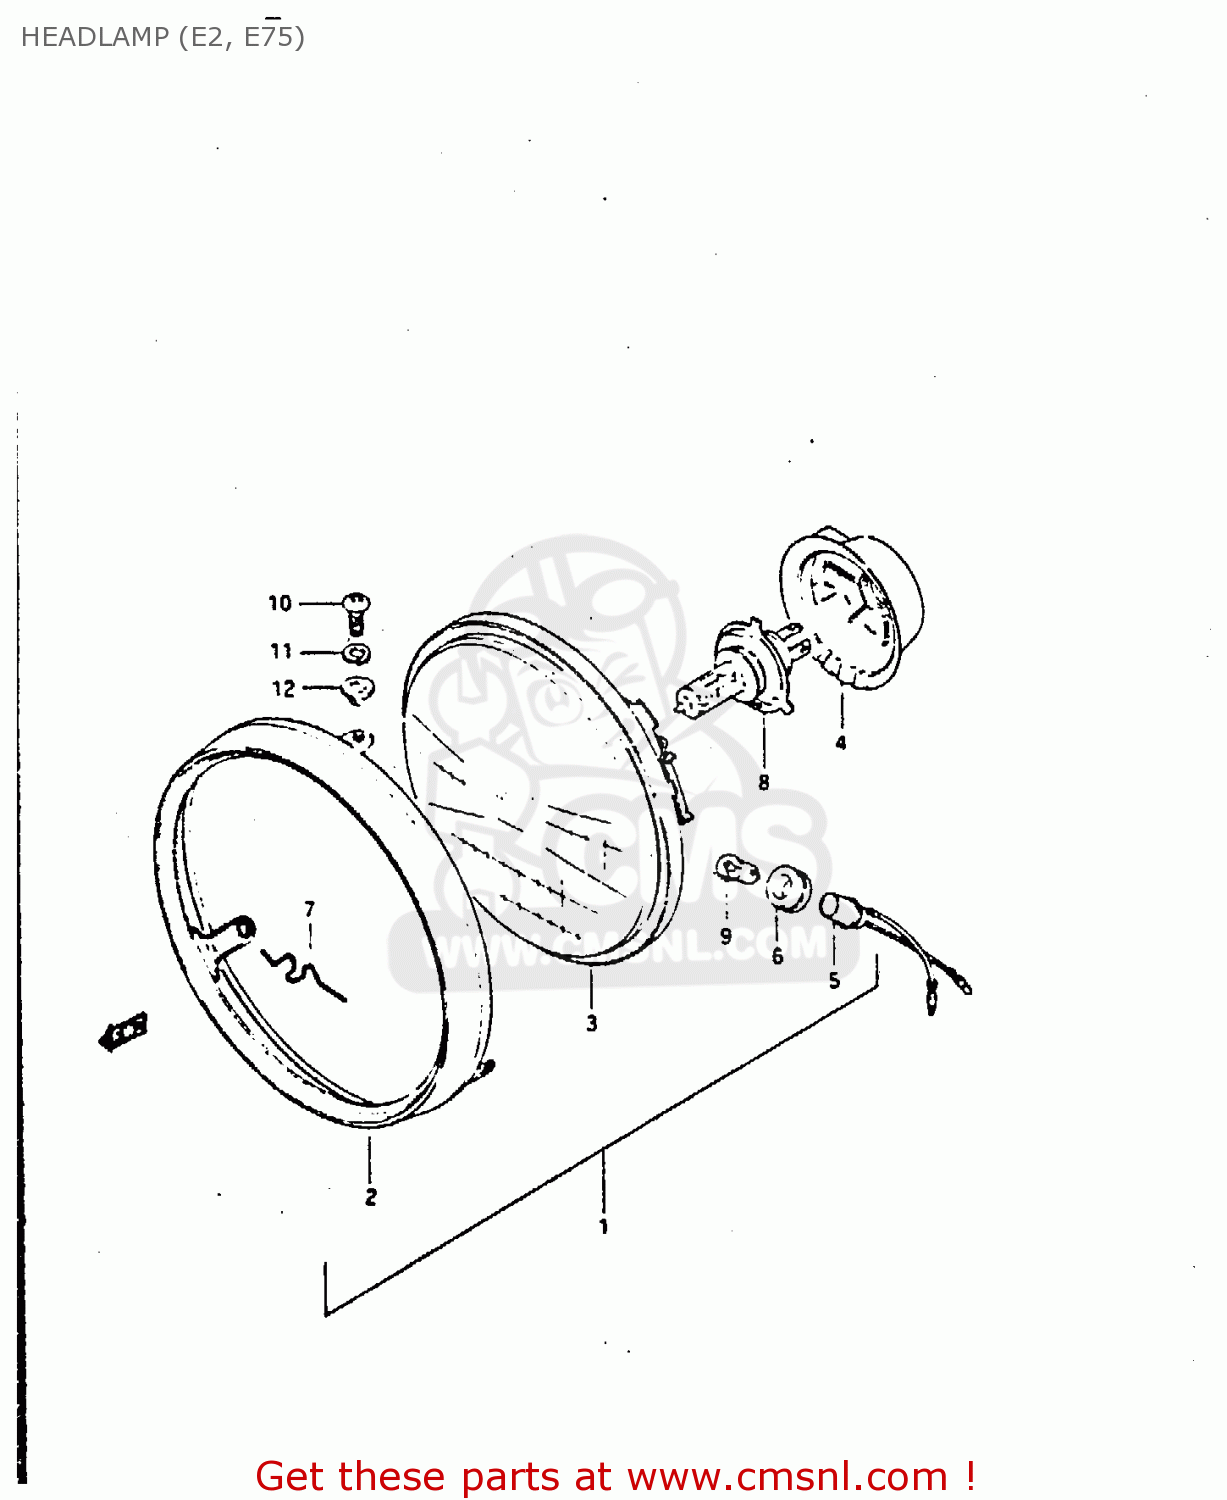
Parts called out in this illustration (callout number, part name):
1	HEADLAMP ASSY
2	RIM
3	LAMP UNIT
4	COVER,SOCKET
5	SOCKET
6	JOINT,RUBBER
7	SPRING
8	BULB(12V60/55W,H4)
9	BULB(12V3.4W,STANLEY,A72A)
10	SCREW
11	WASHER,LOCK
12	WASHER
